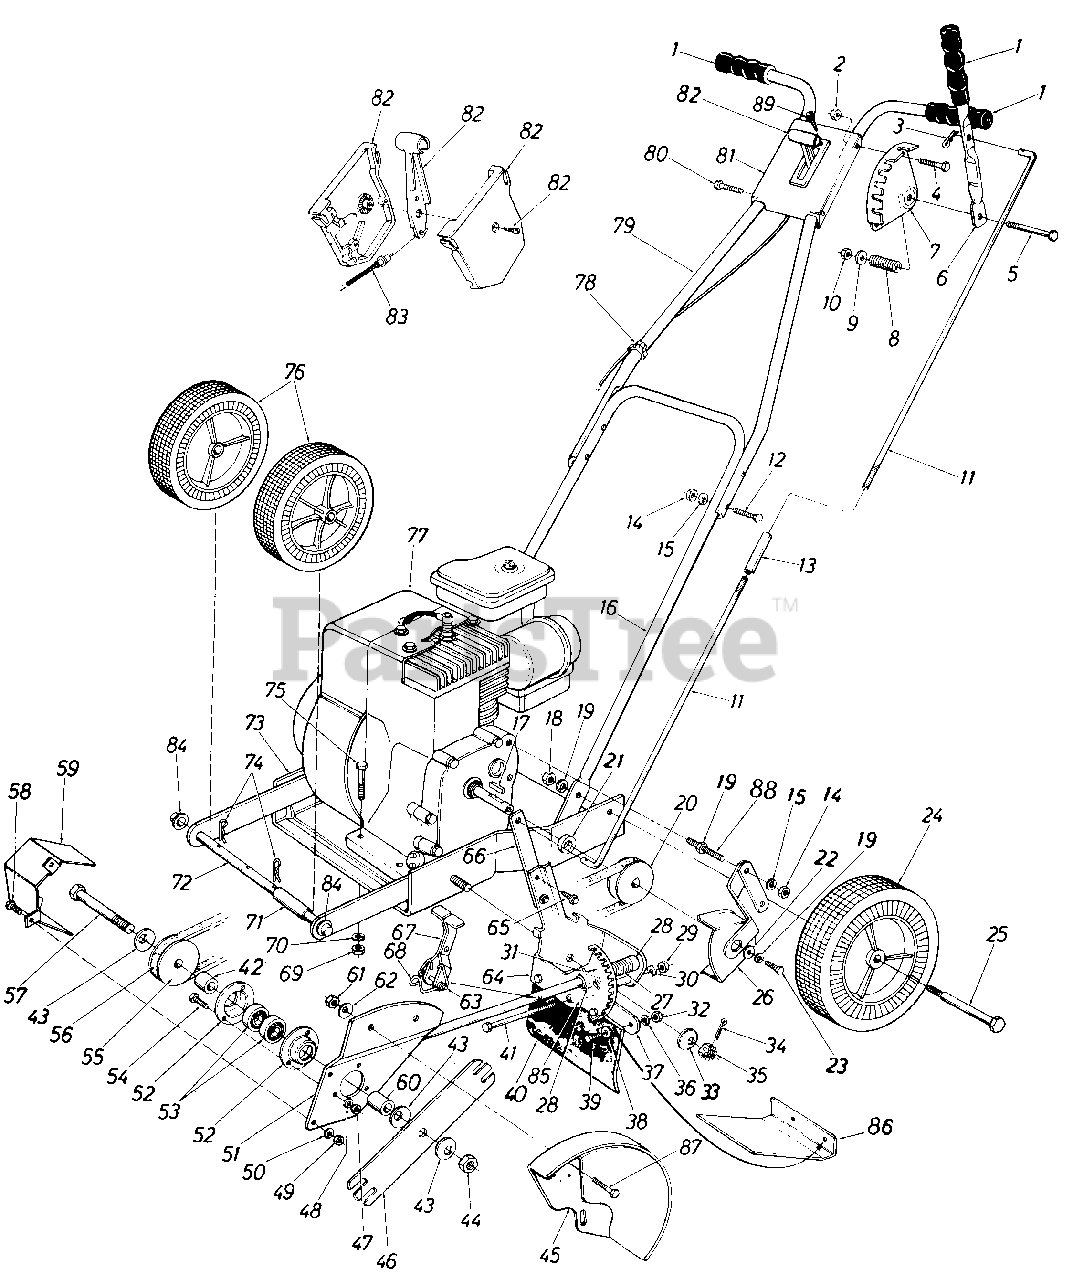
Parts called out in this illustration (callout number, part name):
1	Black Grip
2	Hex L.-Nut 1/4-20 Thd.
3	Cotter Pin 1/8" Dia. x 1.00" Lg.*
4	Hex Bolt 1/4-20 x 1.25" Lg.*
5	Hex Bolt 5/16-18 x 1.75" Lg.*
8	Compression Spring .50" O.D. x 1.38" Lg.
9	Fl.-Wasn .344" I.D. x .62" O.D. x . 063
10	Hex Cent. L.-Nut 5/16-18 Thd.
11	Clutch Rod Halt 3/8" Dia. x 18.25" Lg.
12	Carriage Bolt 1/4-20 x 1.25" Lg.*
13	Rod Adjustment Link
14	Hex Nut 1/4-20 Thd.
15	L-Wash 1/4" 1. D.*
16	Lower Handle
17	Sq. Key 3/16" x 3/16" x .75" Lg.
18	Hex Nut 3/8-16 Thd.*
19	L.-Wash. 3/8" I.D.*
20	Engine Pulley
21	Spacer .75" I.D.
22	Fl.-Wash. .385" I.D. x 1.0" O.D.
23	Hex Bolt 3/8-24 x 1.0" Lg.*
24	Rear Wheel Ass'y. 8 x 1.75
25	Shoulder Bolt .498" Dia. x 1.45" Lg.
26	Belt Guard Ass'y.
27	Compression Spring
28	Bushing
29	Hex Nut 5/16-18 Thd.*
30	L.-Wash. 5/16" I.D.*
31	Spring Pin Spir. 3/16" Dia. x 1.00" Lg.
32	Hex Nut 1/4-20 Thd.*
33	Bell.-Wash. .535" I.D. x 1.50"0.D.
34	Cotter Pin 1/8" Dia. x 1.00" Lg.
35	Hex Slotted Nut 1/2-20 Thd.
36	L.-Wash. 1/4" I.D.*
39	Hex Bolt 1/4-20 x .50" Lg.*
41	Hex Bolt 5/16-18 x 4.5" Lg.*
42	Spacer .635" I.D. x .88" I.D. x 1.030" Lg.
43	Bell.-Wash. .630" I.D. x 1.25" O.D.
44	Hex Ins. L.-Nut 5/8-18 Thd.
47	Hex Nut 1/4-20 Thd.*
48	L.-Wash. 1/4" I.D.*
49	Hex Nut 1/4-20 Thd.*
50	L.-Wash. 1/4" I.D.*
53	Ball Bearing .62" I.D. x 1.38" O.D.
54	Hex Bolt 1/4-20 x.62" Lg.*
55	3/8" "V"-Pulley 2" x 5/8" I.D.
56	"V"-Belt
57	Hex Bolt 5/8-18 x 4.50" Lg.*
58	Hex Bolt 1/4-20 x .50" Lg.*
60	Sleeve .632" I.D. x .875" O.D. x .90" Lg.
61	Hex Nut 5/16-18 Thd.*
62	Bell.-Wash. .345" I.D. x .88" O.D.
63	Spring Pin Spir. 1/4" Dia. x 2.00" Lg.
68	Torsion Spring
69	Hex Nut 5/16-18 Thd.*
70	L.-Wash. 5/16" I.D.*
71	Spacer .50" I.D. x .62" O.D. x 1.62" Lg.
72	Axle .50" Dia. x 8.75" Lg.
73	Base Ass'y.
74	Hair Pin Cotter 1/2" Dia.
75	Hex Bolt 5/16-18 x 1.50" Lg.*
76	Front Wheel Ass'y. 7 x 1.50
77	Engine
78	Cable Tie
79	Upper Handle
80	Hex Bolt 1/4-20 x 1.00" Lg.*
81	Handle Support Plate
82	Throttle Control Box Ass'y.
83	Throttle Control Wire 30" Lg.
84	Push Cap 1/2" Dia.
85	Spacer .386" I.D. x .510" O.D. x 3.765" Lg.
88	Stud 1/4-20 x 2.12" Lg.
89	Truss Machines AB Self-Tapping Screw
